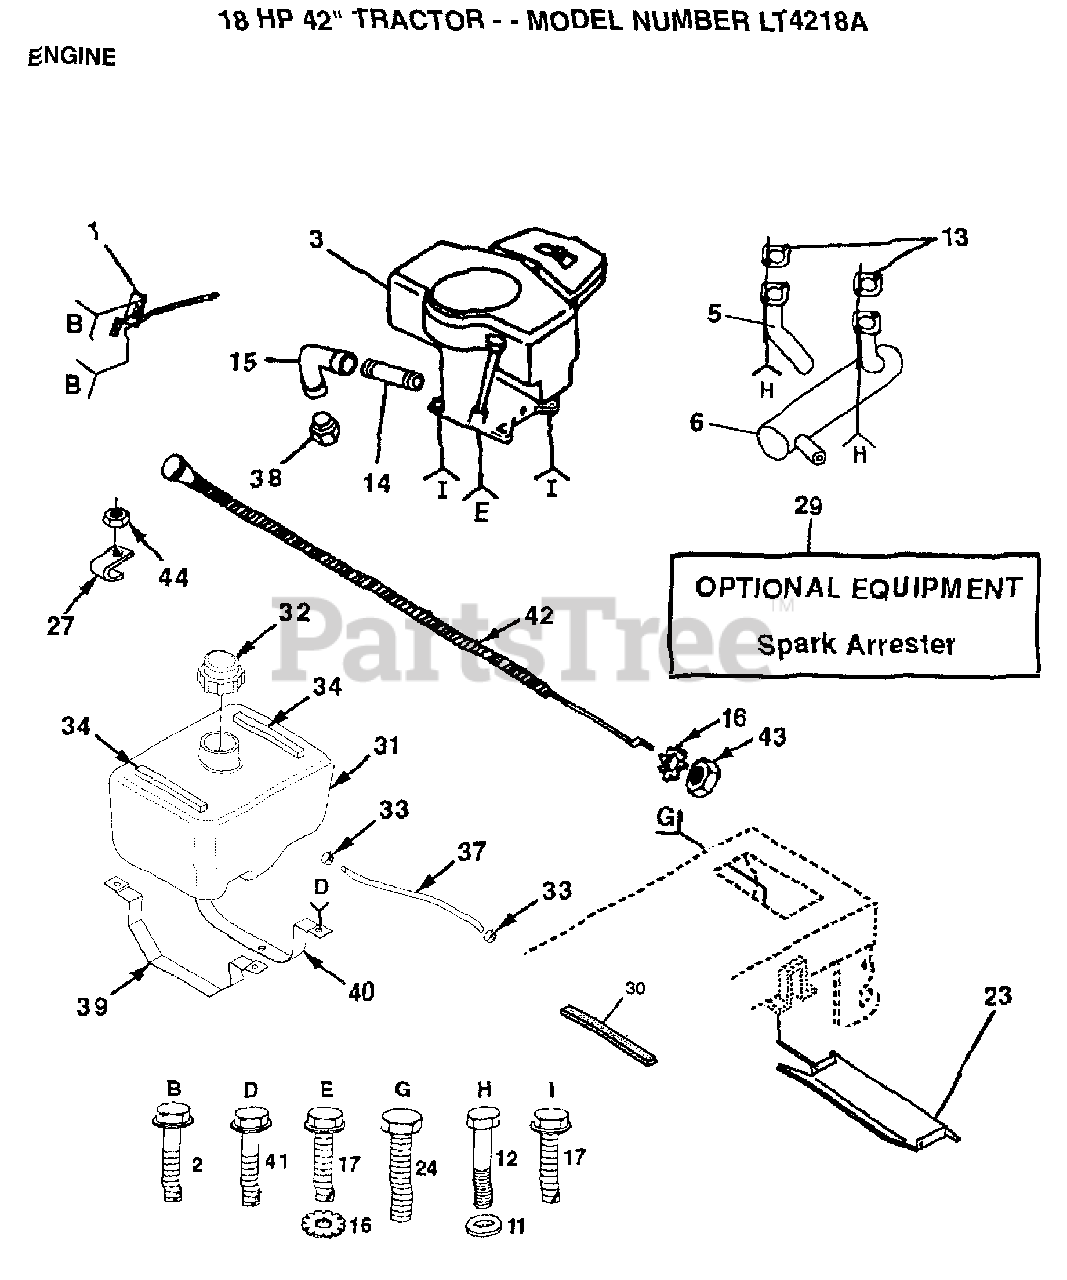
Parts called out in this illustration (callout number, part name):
1	CONTROL.THROTTL
2	SCREW LT
3	ENGINE B&S 18HP
4	NUT
5	LOCKWASHER
11	LOCKWASHER
12	EXHAUST TUBE T
14	PIPE NIPPLE LT
15	ELBOW
17	SCREW LT
23	HEAT SHIELD
24	SCREW
27	CLIP T
31	TANK FUEL 1.9 NAT
32	CAP ASM FUEL
33	HOSE CLAMP
34	"STRIP,FORM"
37	LINE FUEL
39	STRAP TANK FUEL
40	STRAP TANK FRONT
41	SCREW
42	CHOKE CONTROL
